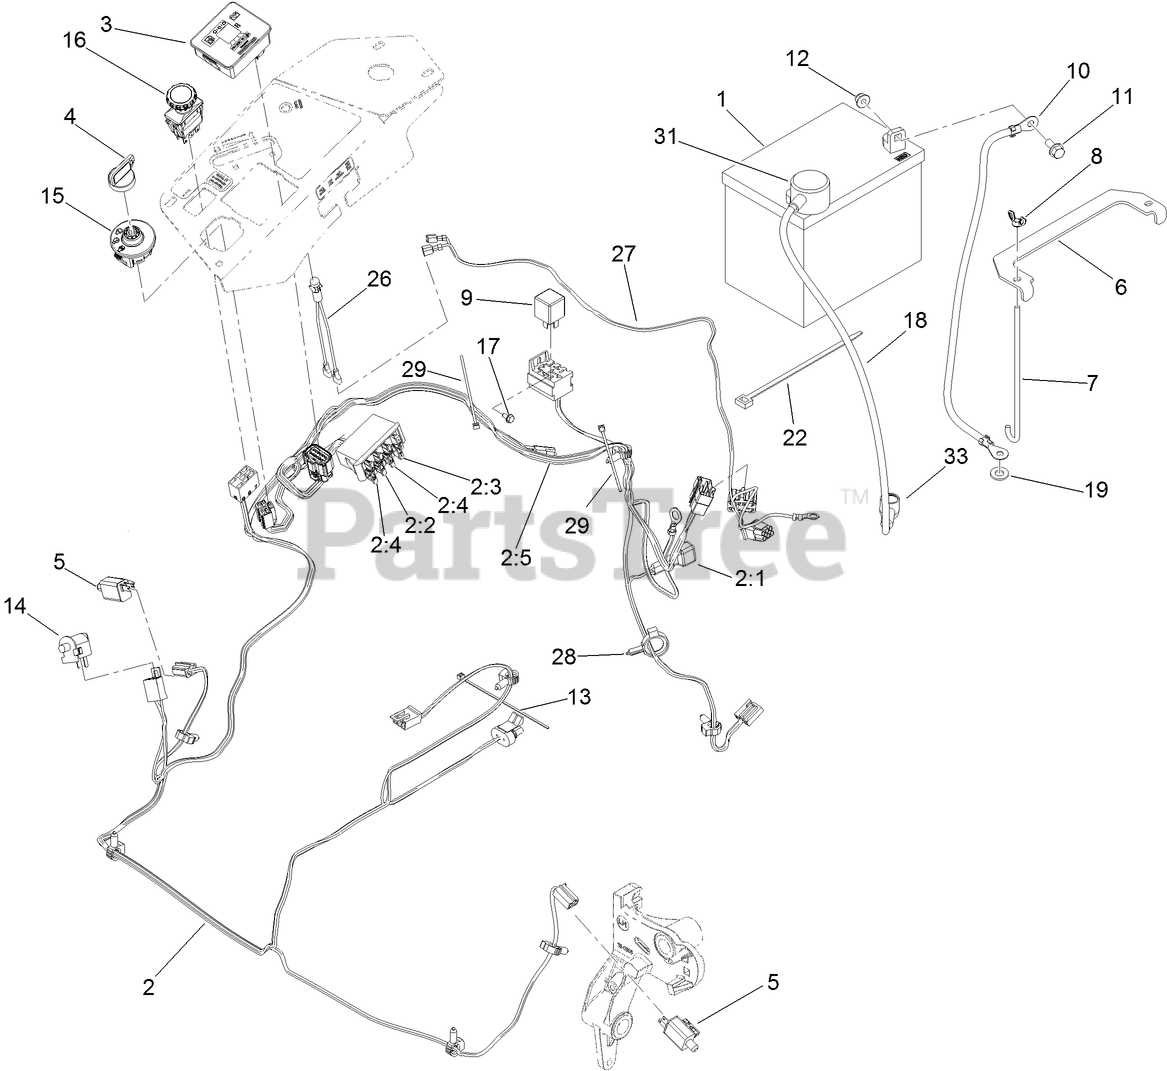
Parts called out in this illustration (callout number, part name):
1	BATTERY
2	HARNESS-WIRE, MAIN
2:2	FUSE-BLADE, 10 AMP
2:3	FUSE-BLADE, 15 AMP
2:4	FUSE-BLADE, 25 AMP
2:5	CAP-PLUG
3	FUEL/HOUR METER ASM
4	KEY-IGNITION
5	SWITCH
6	STRAP-TIE DOWN, BATTERY
7	BOLT-HOLDDOWN
8	WINGNUT
10	CABLE-BATTERY, NEGATIVE
11	SCREW-HHF
12	NUT-HF, NI
13	TIE-CABLE
14	SWITCH-BAIL
15	SWITCH-IGNITION
16	SWITCH-PTO, 10 AMP
17	SCREW-HWH
18	CABLE-BATTERY, POSITIVE
19	WASHER-FLAT
22	TIE-PLASTIC
26	INDICATOR-LED, RED
27	HARNESS-LIGHT, INDICATOR
28	CLAMP-HOSE
29	TIE-CABLE
31	INSULATOR-BATTERY
33	INSULATOR-SOLENOID
